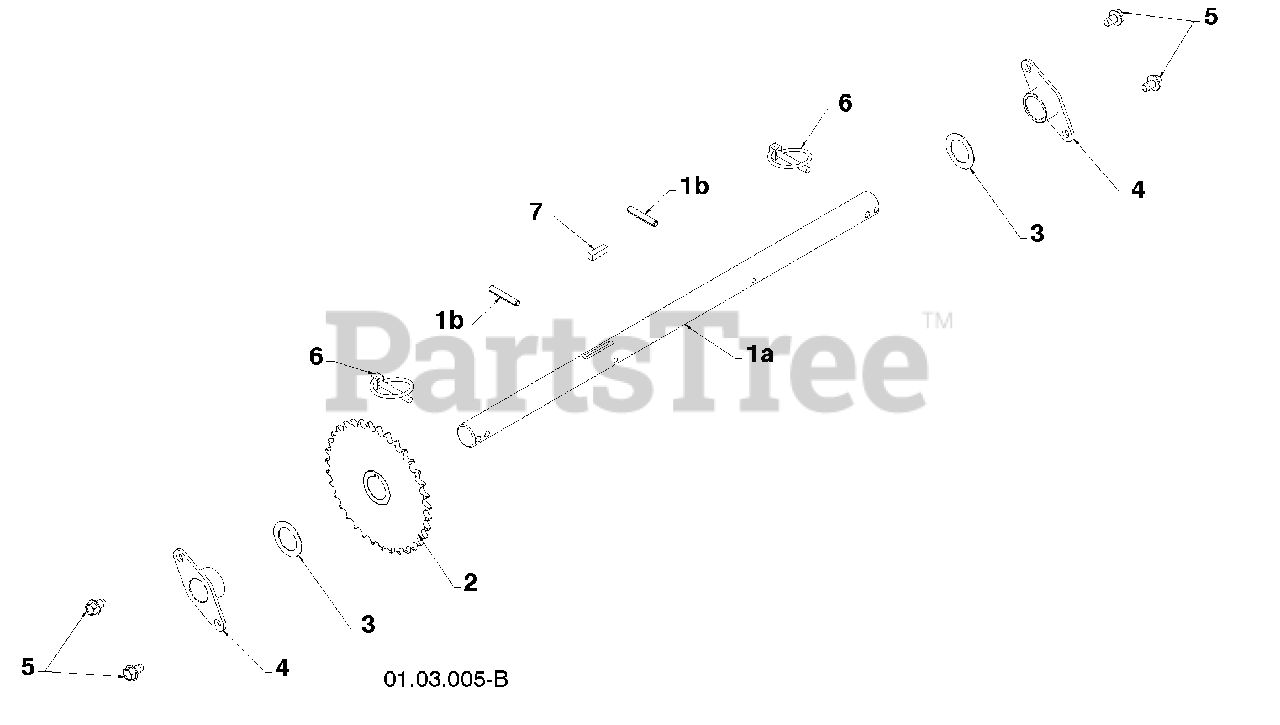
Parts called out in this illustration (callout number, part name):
1	(assy of 1a,1b) AXLE ASSEMBLY
2	SPROCKET
3	THRUST WASHER
4	BEARING
5	BOLT 5/16-18 X .500
6	CLIK PIN
7	SQUARE KEY
